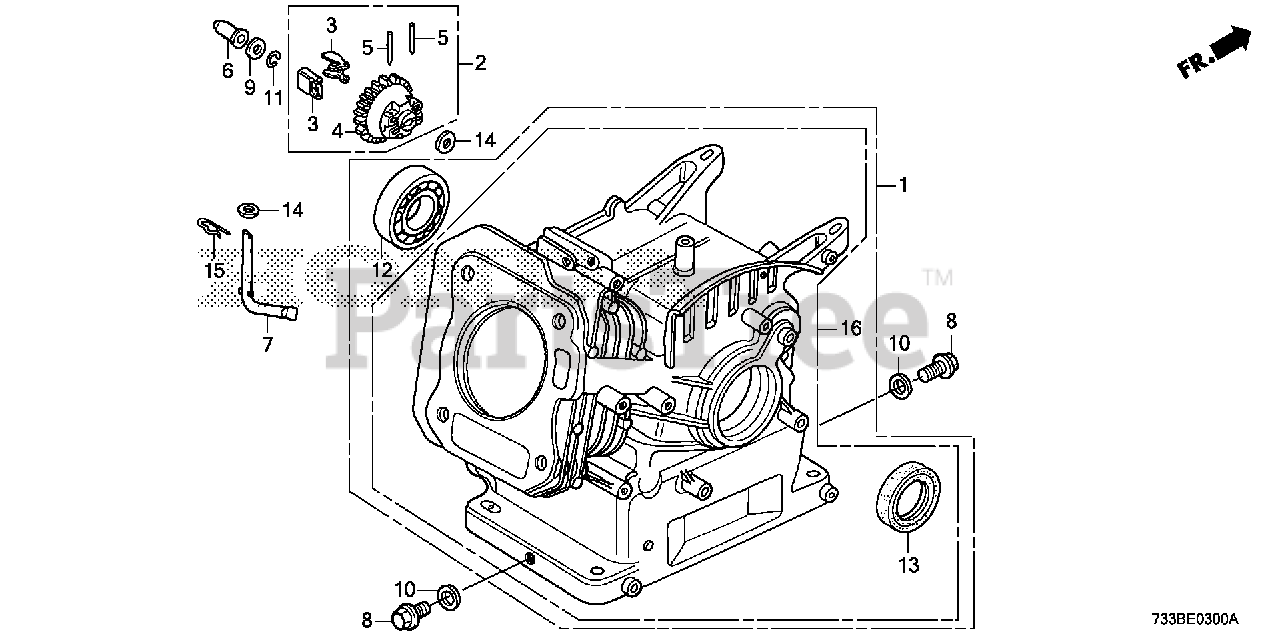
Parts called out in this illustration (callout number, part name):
2	GOVERNOR ASSY.
5	PIN, GOVERNOR WEIGHT
6	SLIDER, GOVERNOR
7	SHAFT, GOVERNOR ARM
8	BOLT, DRAIN PLUG
9	WASHER, THRUST (6MM)
10	WASHER, DRAIN PLUG (10.2MM)
11	CLIP, GOVERNOR HOLDER
13	OIL SEAL (25X41X6)
13	OIL SEAL (25X41X6) (ARAI) (NOT AVAILABLE)
14	WASHER, PLAIN (6MM)
15	PIN, LOCK (8MM)
16	CYLINDER ASSY.
